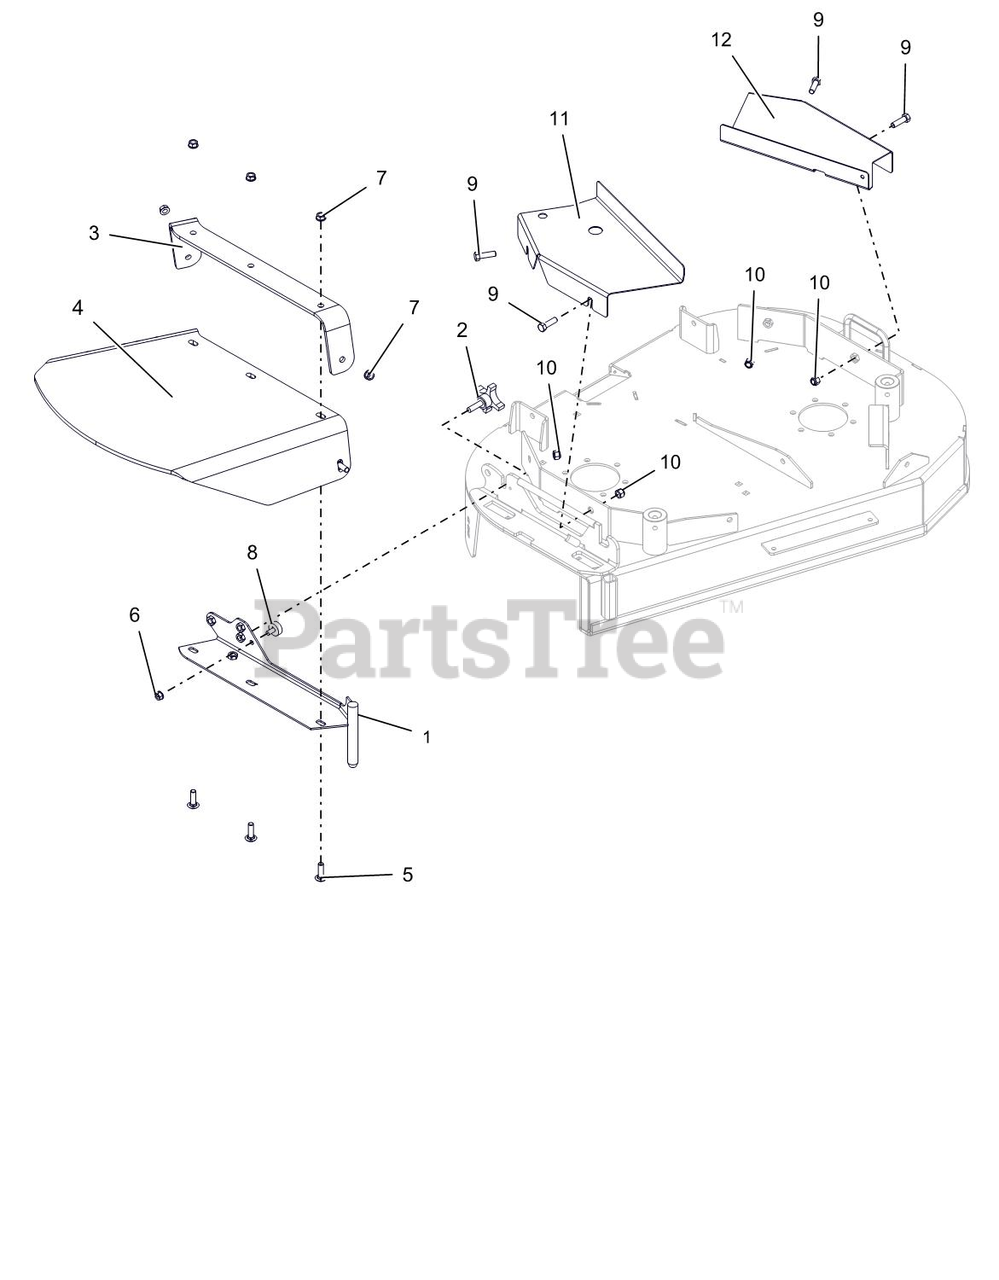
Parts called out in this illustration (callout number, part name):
1	WLDT. DISCHARGE
2	KNOB, 3/8 X 1.25 - 4 PRONG
3	STRAP, GRAVELY WLK RUBBER DIS
4	SHIELD, WALK RUBBER DISCHARGE
5	BLT,RHSSN-.375X1.25 G5 RIE5230
6	NUT,SPNLK-FLG .312-18 ZC120
7	NUT, SPNLK-FLG .38-16 G5ZC120
8	BUMPER, RUBBER
9	BLT, HEX .38-16X1.25 G5 ZCC
10	NUT,NYL .38-16 G5 ZCC
11	COVER, DECK 36 - RH
12	COVER, DECK 36 LH
